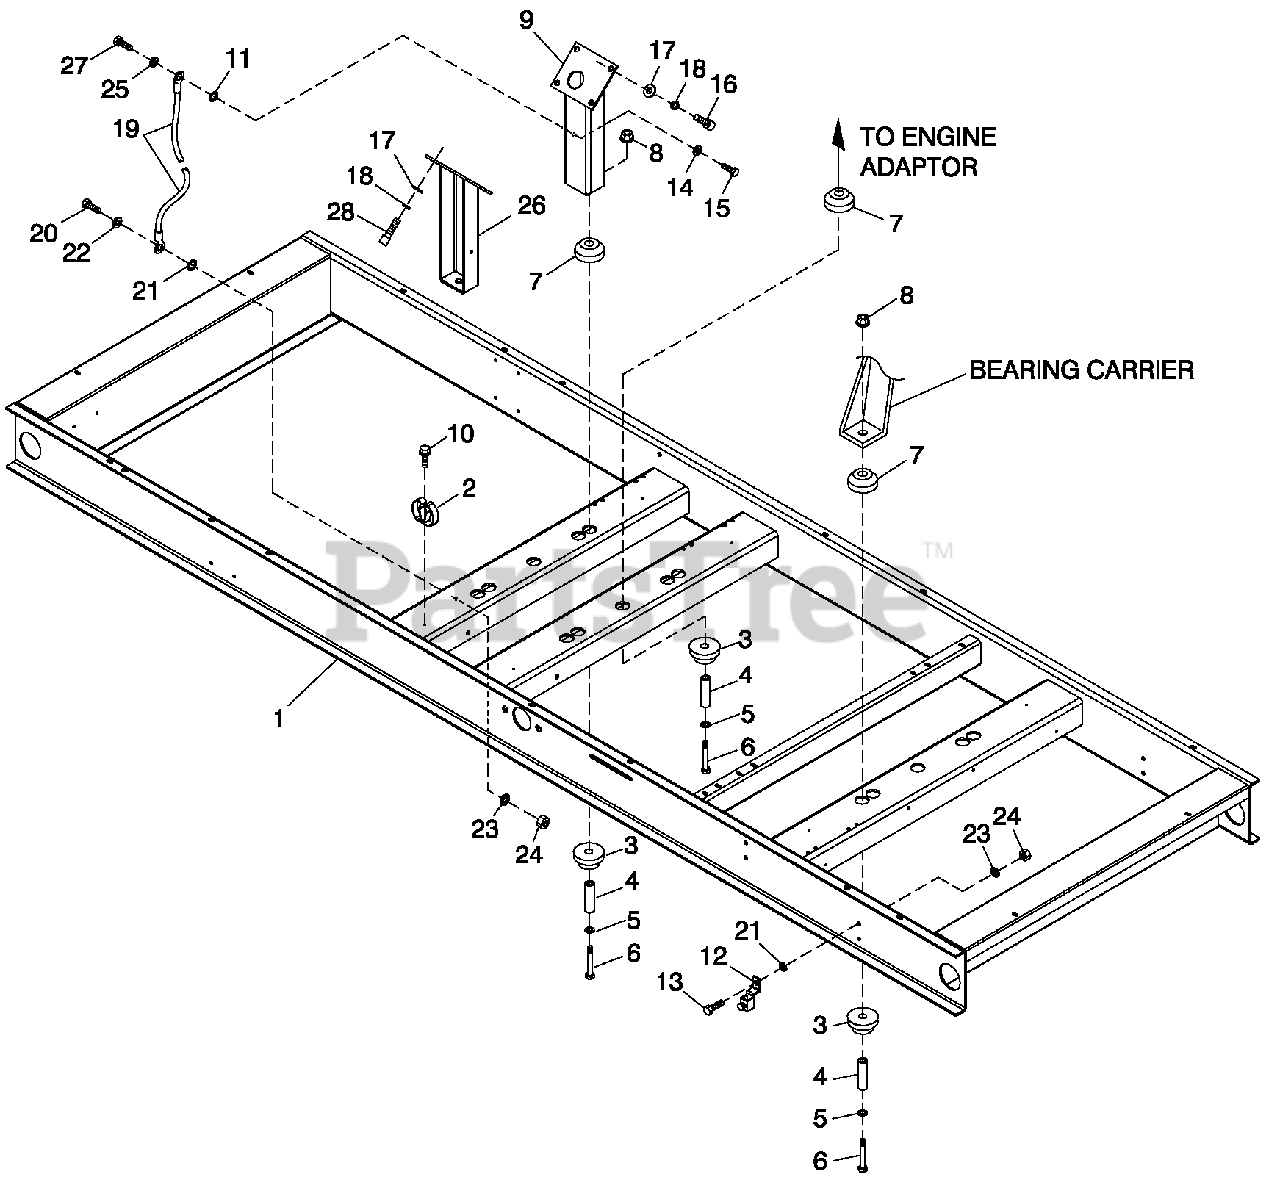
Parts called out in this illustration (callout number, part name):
1	BASE CPL 150KW2P
2	SPRING CLIP HOLDER ,37-.62
3	DAMPENER VIBRATION
4	SPACER .49 X .62 X 1.87 PWDR/ZINC
5	WASHER FLAT M12
6	SCREW HHC M12-1.75 X 85 G8.8
7	DAMPENER VIBRATION 50 WHITE
8	NUT LOCKING M12-1.75
9	SUPPORT ENG 5.4L LH/RH 6.8L RH
10	SCREW HHTT M4-0.7X8BP
11	WASHER SHAKEPROOFINT1/4
12	LUG SOLDERLESS 3/0-#4 X 13/32 CU
13	SCREW HHC M8-1.25X 25 G8.8
14	WASHER FLAT 1/4-M6 ZINC
15	NUT HEX M6 X 1.0 G8 YEL CHR
16	SCREW SHC M10-1.5 X 30 G12.9
17	WASHER FLAT 3/8-M10 ZINC
18	WASHER LOCK M10
19	ASSY WIRE 14.00"
20	SCREW HHC M8-1.25X 30 G8.8
21	WASHER SHAKEPROOF INT 3/8
22	WASHER LOCK M8-5/16
23	WASHER FLAT 5/16-M8 ZINC
24	NUT HEXM8-1.25G8YEL CHR
25	WASHER LOCK M6-1/4
26	SUPPORT, ENGINE 6.8L LH SIDE
27	SCREW HHC M6-1.0X 30 G8.8
28	SCREW SHC M10-1.5 X 60 G12.9
